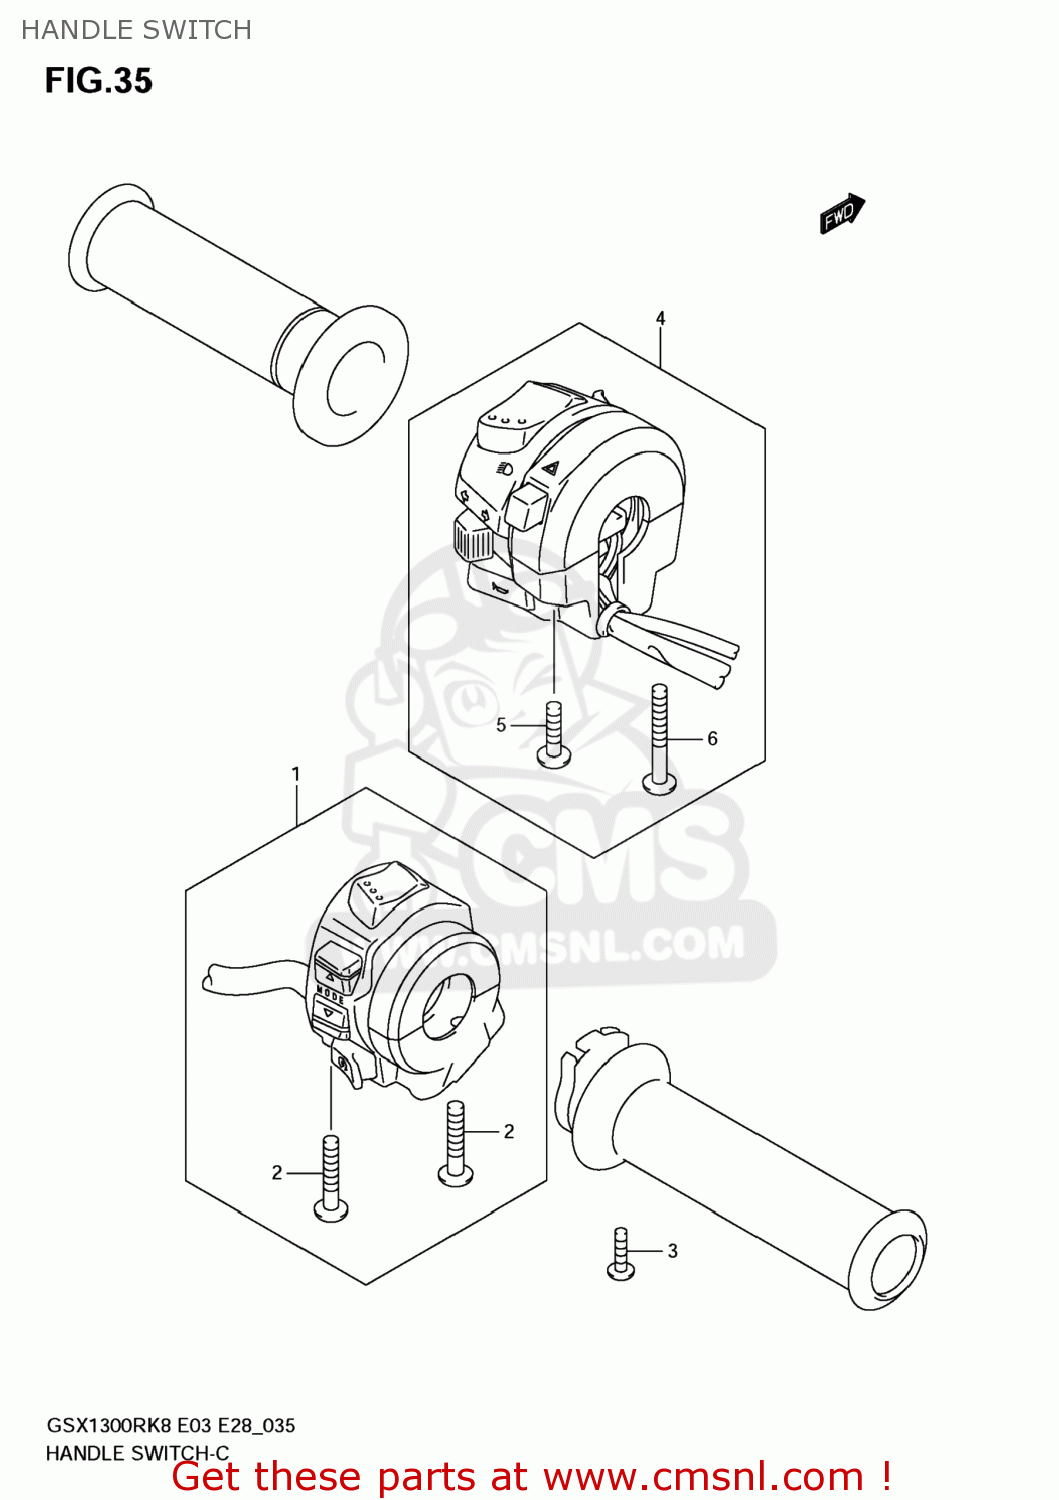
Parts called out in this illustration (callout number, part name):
1	SWITCH ASSY,HANDLE,R
2	SCREW
3	SCREW
4	SWITCH ASSY,HA
5	SCREW
6	SCREW
